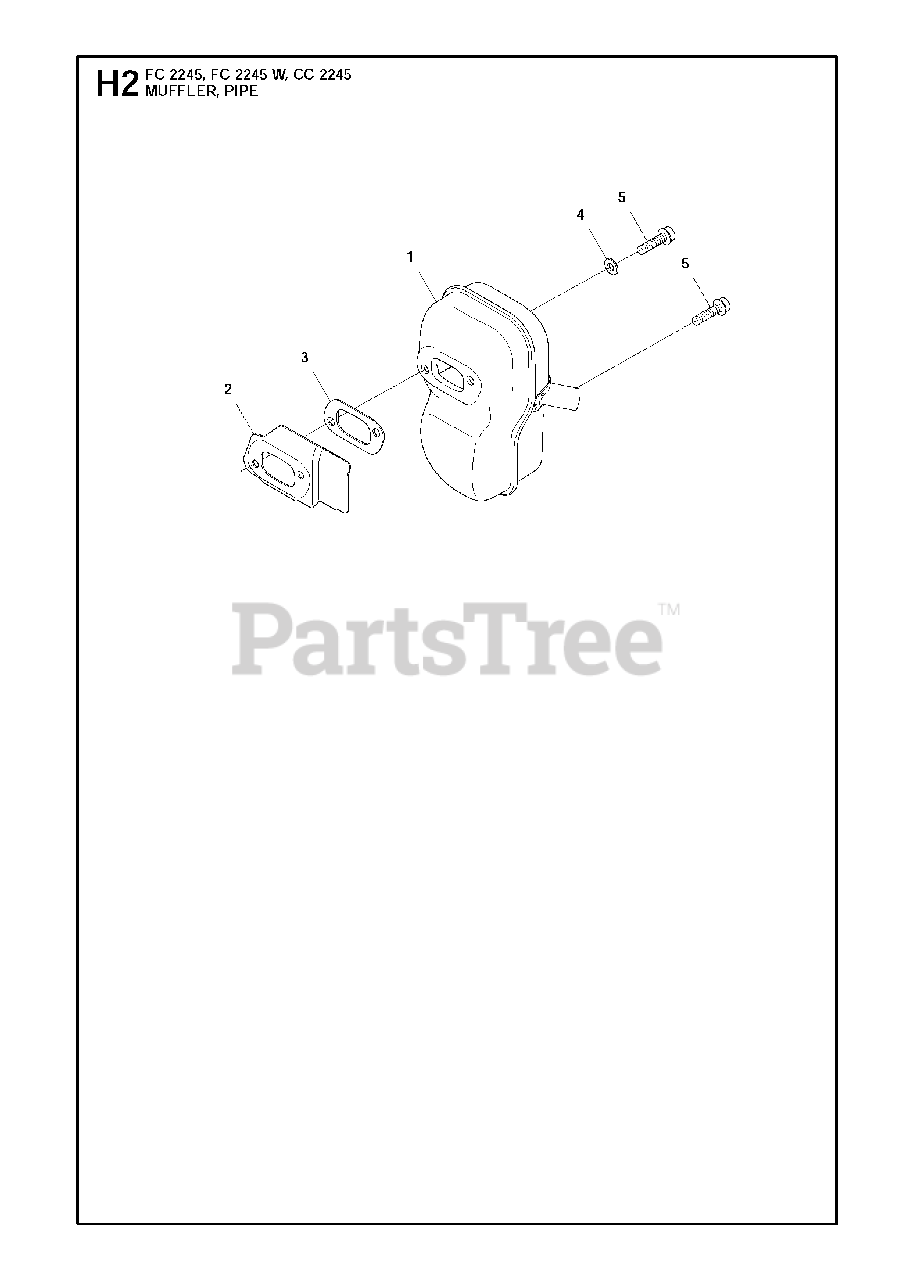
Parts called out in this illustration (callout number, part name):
1	MUFFLER ASSY
2	HEAT DEFLECTOR
4	DOUBLE WASHER
